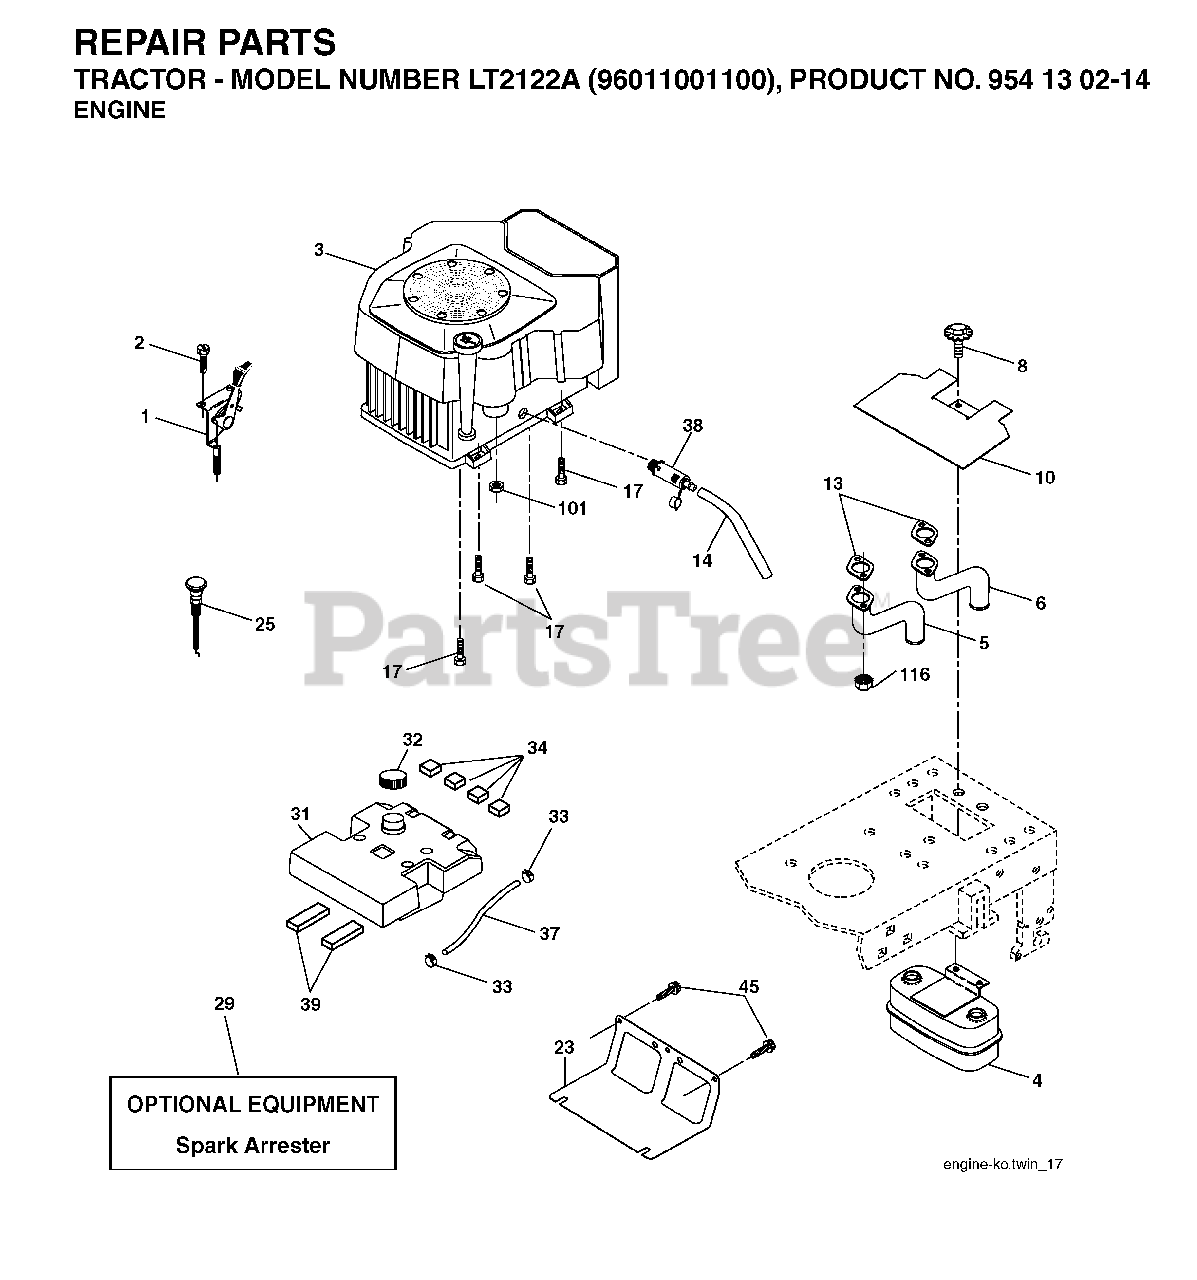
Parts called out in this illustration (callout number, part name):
1	CONTROL.THROTTLE.KAWA
2	SCREW
4	MUFFLER.TWIN.CYL.LOW.TONE
5	PIPE-EXHAUST LH
6	PIPE-EXHAUST RH
8	BOLT, 5/16-18 X 1 3/4
10	RP SHIELD HEAT MUFFLER
13	GASKET.EXHAUST.KOHL.CV18-CV26
14	TUBE, DRAIN OIL ASM.
23	SHEILD.BROWNING.DBR.GUARD
25	CONTROL, CHOKE
29	ARRESTER SPARK (OPTIONAL)
31	TANK.FUEL(3.5.GAL)
32	FUEL CAP
33	HOSE CLAMP
34	PAD-SPACER LT
38	PLUG DRAIN OIL EASY
39	PAD IDLER TI
45	SCREW, 3/8-16X3/4
101	FLANGE NUT
116	NUT.HEX.FLANGE.TOPLOCK
